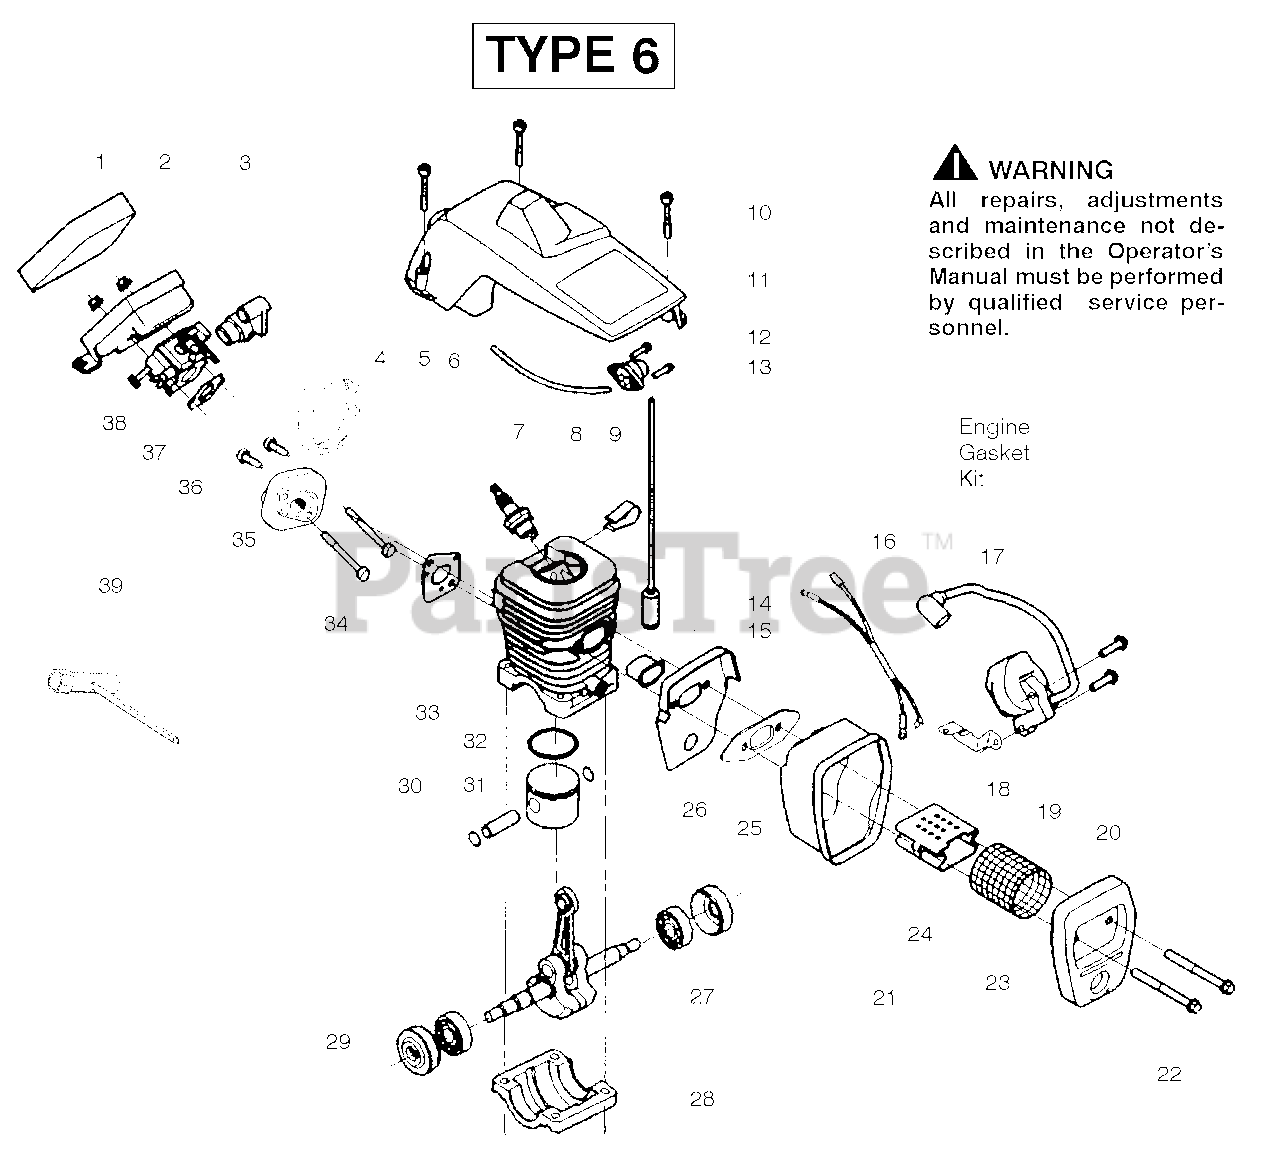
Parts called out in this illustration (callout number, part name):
1	Foam- Air Filter
3	Grommet-Carb Adjust
4	Seal-Carb Adapter
5	Adapter-Carb.
6	Kit-Fuel Line (Small)
7	Spark Plug (RCJ-7Y)
8	Kit-Cylinder
9	Clip-High Tension Lead
11	Shield-Cylinder
12	Assy- Air Purge
14	Assy-Fuel Pick-up
15	Insulator-Heat
16	Assy. -Wire Harness
17	Kit-Engine Gasket
19	Module- Ignition
21	Assy-Muffler
24	Diffuser-Muffler
25	Gasket-Muffler(kit)
26	Backplate-Muffler
27	Assy. - Crankshaft
28	Cap-Crankcase
29	Assy.-Seal & Bearing
30	Kit-Piston
31	Retainer-Piston Pin
32	Ring - Piston
33	Gasket - Adapter(kit)
36	Gasket - Carb.(kit)
37	Kit-Carburetor (WT-624)
38	Housing- Air Filter
